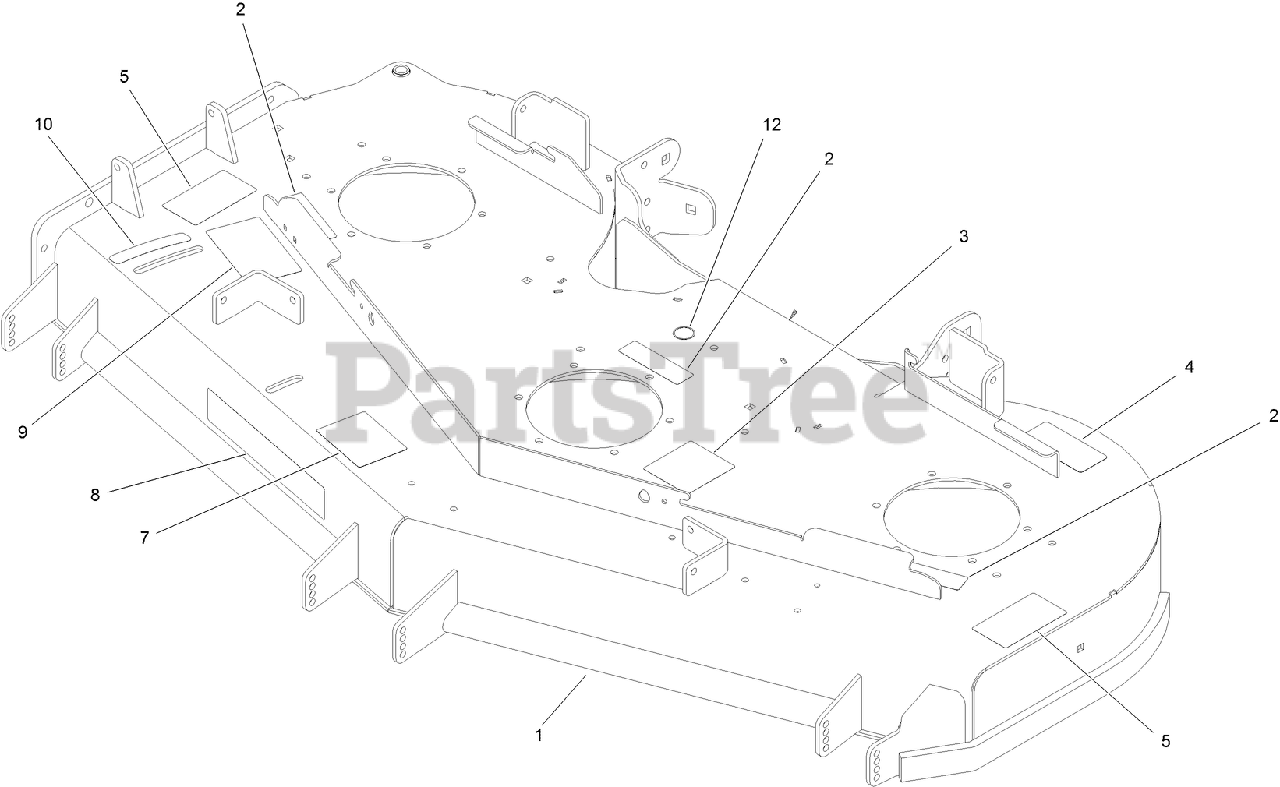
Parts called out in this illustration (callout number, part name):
1	DECK DECAL ASM
2	DECAL-COVER, MISSING
3	DECAL-ROUTING, DECK BELT
4	DECAL-TORQUE, BLADE BOLT
5	DECAL-DANGER
7	DECAL-SCALP, ANTI
9	DECAL-ADJUSTMENT, BAFFLE
10	DECAL-SETTING, BAFFLE
12	DECAL-GREASE
